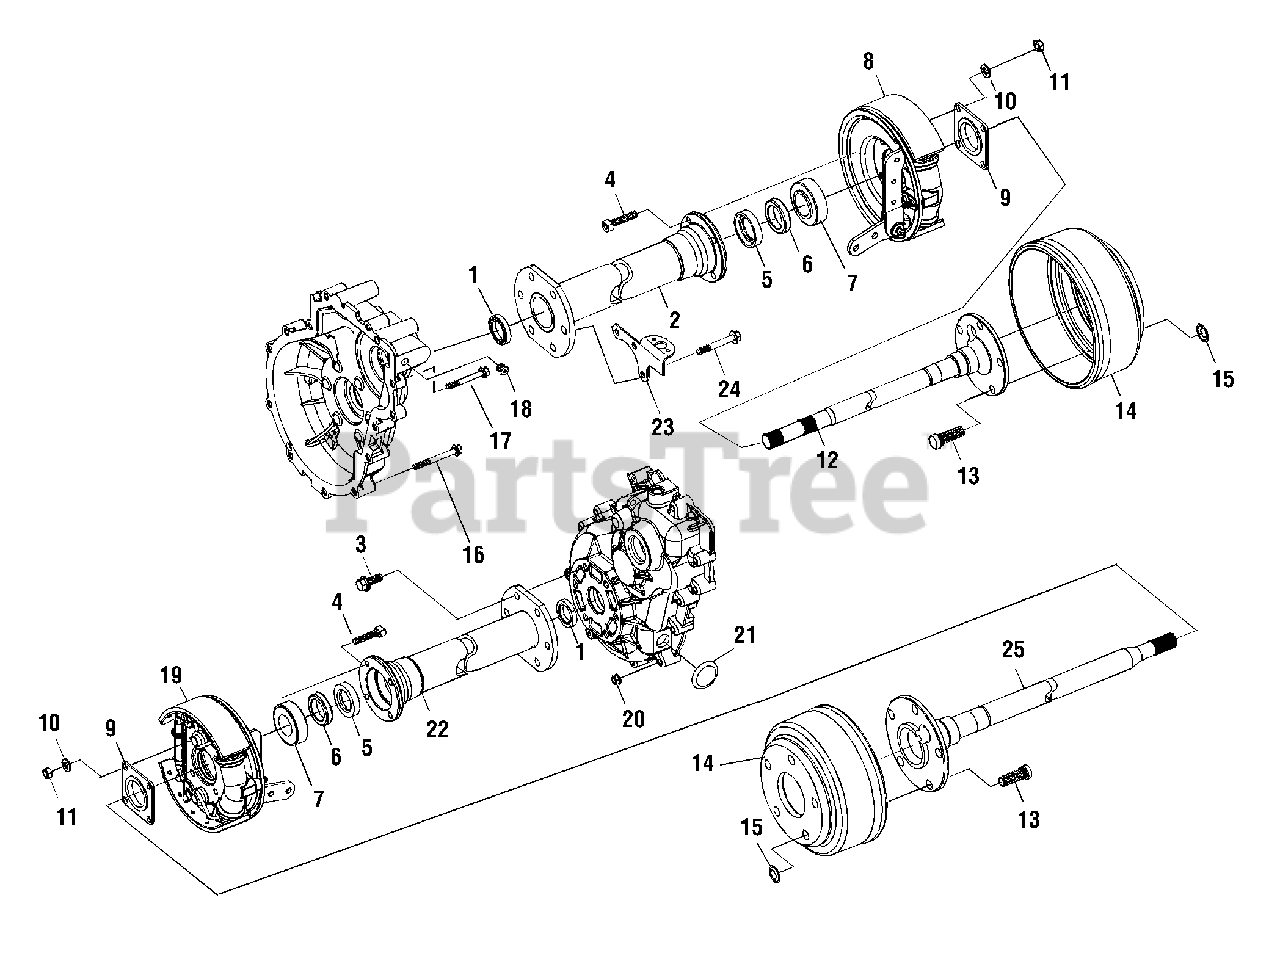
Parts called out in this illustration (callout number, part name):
2	Assembly, Tube
3	Screw, Flange Head
4	Screw, Socket Head
6	Ring, Retainer
7	Ass'y, Bearing, Tapered Roller
8	Assembly, Brake RH
9	Seal, Oil
10	Washer, Flat
14	Drum, Brake
15	Nut, Spring
16	Screw, Flange Head
17	Screw, Flange Head
19	Assembly, Brake LH
21	Plug, Rubber
22	Assembly, Tube
23	Bracket, Differential Lock Actuator
24	Screw, Flange Head
